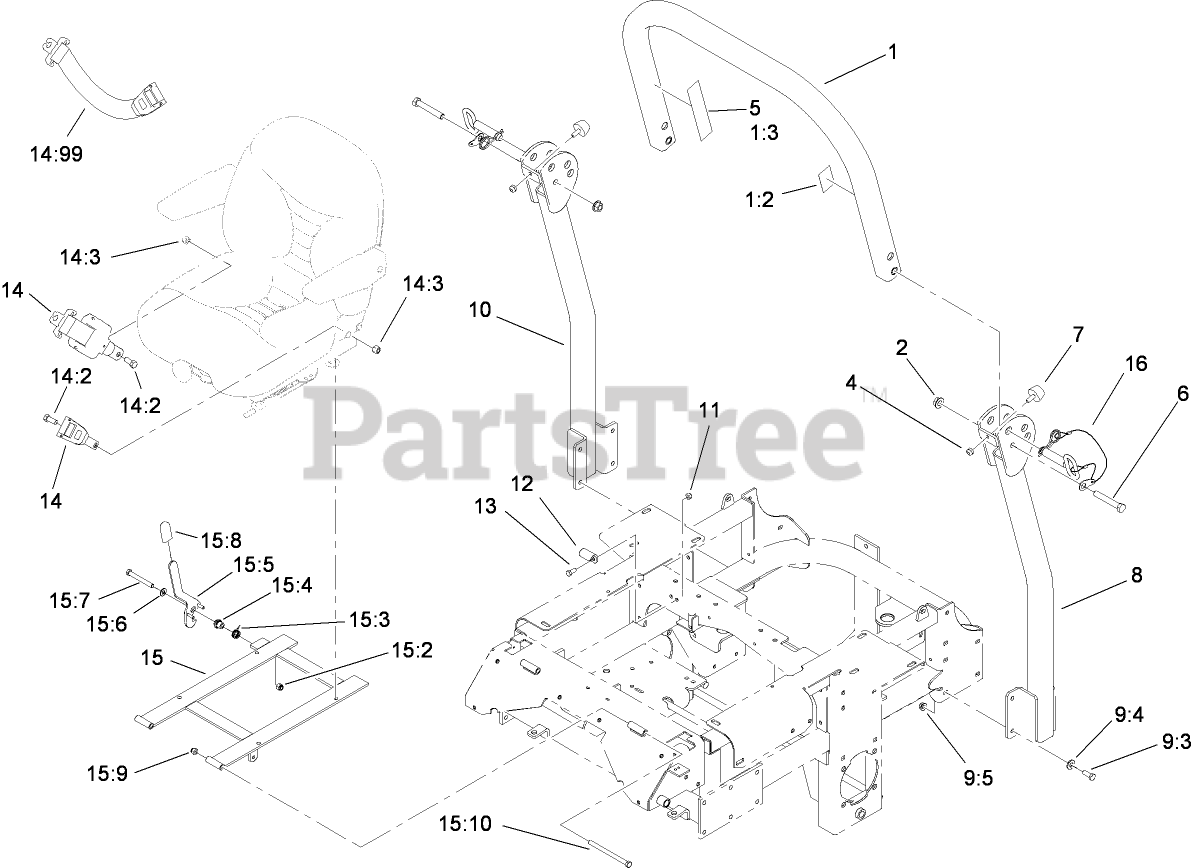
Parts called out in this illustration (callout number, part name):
1	Upper Tube ASM
1:2	DECAL-ROPS
1:3	DECAL-WARNING, FOLDING ROPS
2	NUT-HF
4	NUT-LOCK, NI
5	DECAL-WARNING
6	SCREW-HH
7	BUMPER-RUBBER
8	TUBE-SUPPORT, LH
9:3	SCREW-HH
9:4	WASHER-BELLEVILLE
9:5	NUT-HHF, WHIZ
10	TUBE-SUPPORT, RH
11	NUT-LOCK, NI
12	Catch-Latch, Seat
13	SCREW-HH
14	RETRACTABLE SEATBELT KIT
14:2	SCREW-HH
14:3	NUT-LOCK
14:99	SEAT BELT EXTENSION KIT
15	SEATFRAME ASM
15:2	NUT-LOCK, NI
15:3	SPRING-TORSION
15:4	BUSHING-LATCH, SEAT
15:5	LATCH ASM
15:6	WASHER-FLAT
15:7	SCREW-HH
15:8	GRIP-LEVER
15:9	NUT-LOCK, NI
15:10	SCREW-HH
16	PIN-FOLD, ROPS
